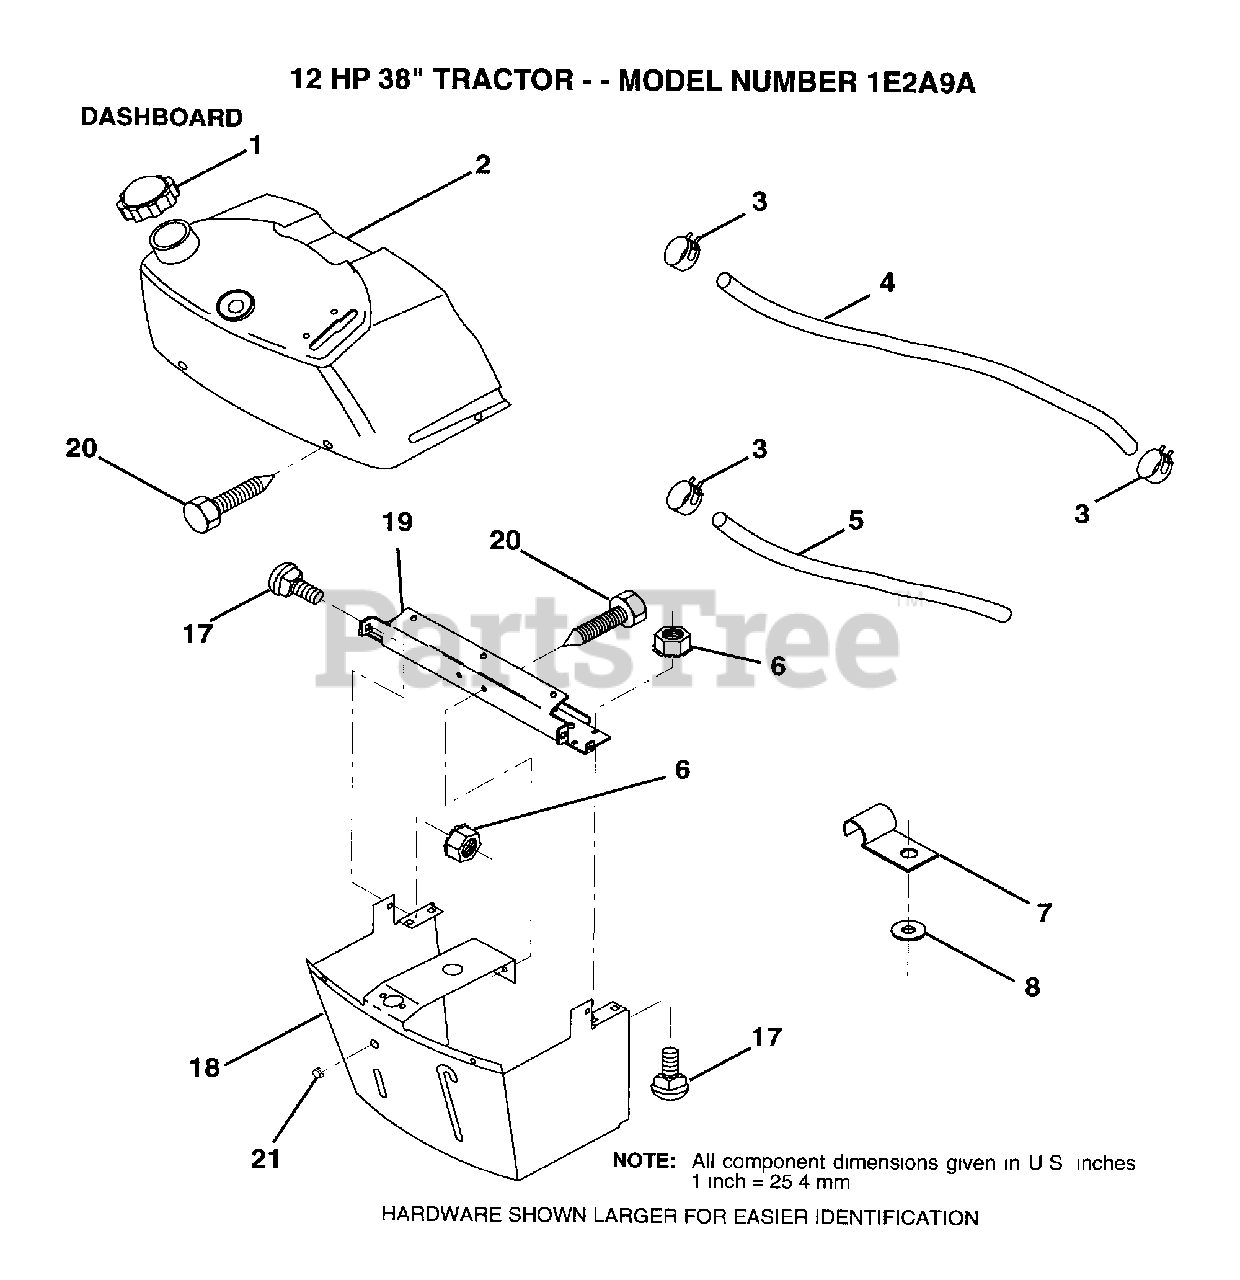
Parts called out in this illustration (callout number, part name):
1	CAP.FUEL.N/VENT
2	TANK.ASM.DASH.LR
3	HOSE CLAMP
5	FUEL LINE T
6	NUT
7	CLIP T
8	WASHER PM
17	BOLT
18	SUPT ASM DASH
19	CROSS BRACE
20	SCREW.1/4-20X1/2
21	PLUG DOME
